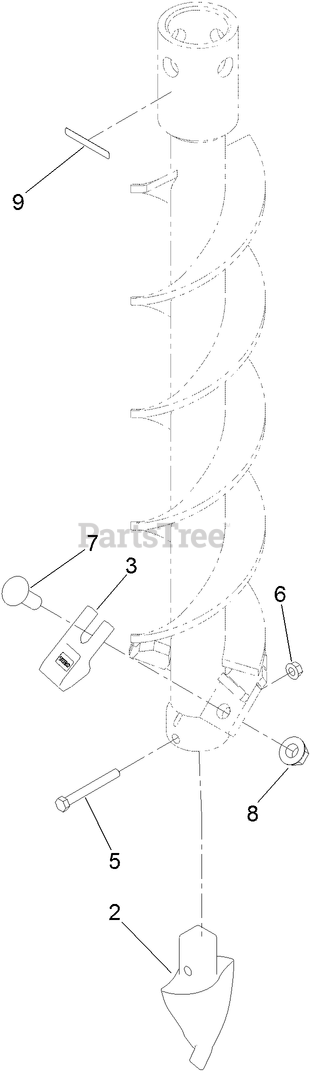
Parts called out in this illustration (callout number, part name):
2	PILOT-AUGER
3	TOOTH-OUTER
5	SCREW-HH
6	NUT-HF
7	SCREW-CARR
8	NUT-FLANGE
9	DECAL-WARNING
